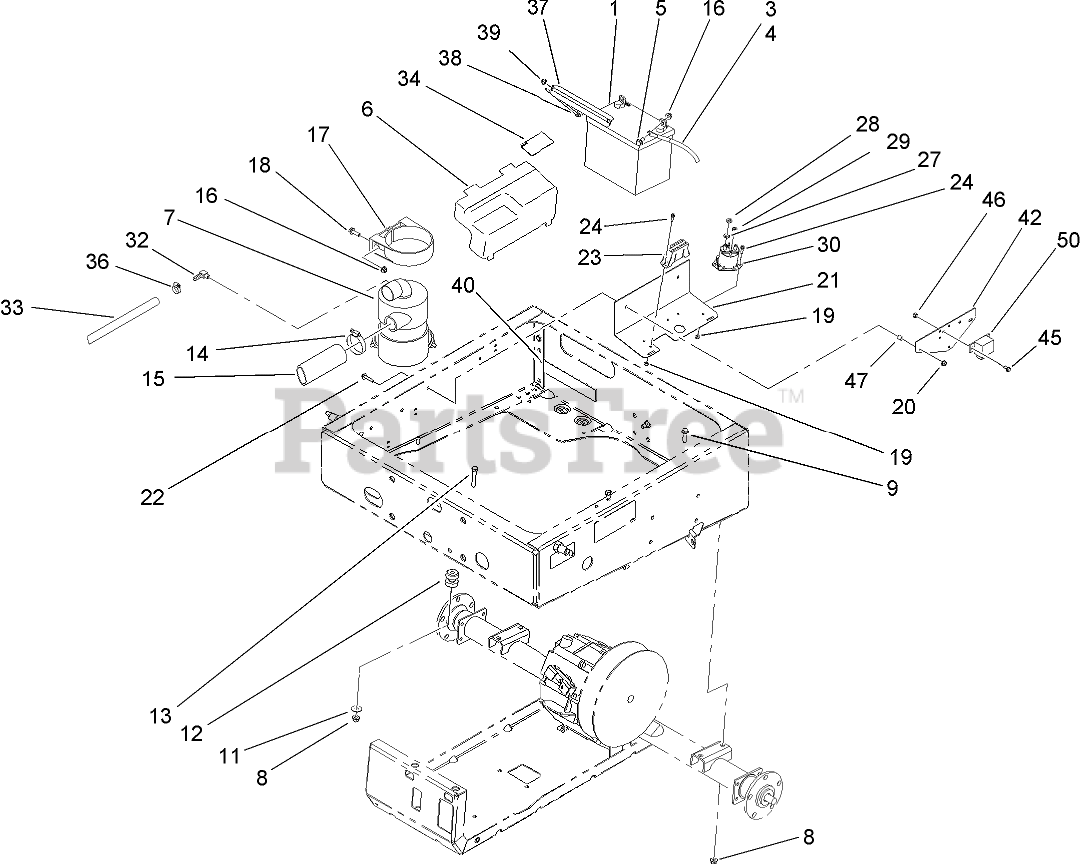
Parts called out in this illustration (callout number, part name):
1	BATTERY-DRY
3	CABLE-NEGATIVE
4	CABLE-POSITIVE
5	SCREW-HHF
6	COVER-ELECTRICAL
7	AIR CLEANER ASM
8	NUT-HF, NI
9	SCREW-HHF
11	WASHER-FLAT
12	MOUNT-ISO
13	SCREW-HH
14	CLAMP-HOSE
15	HOSE-INTAKE
16	NUT-HF, NI
17	BRACKET-MOUNTING
18	SCREW-HHF
19	NUT-LOCK, NI
20	NUT-HHF
21	MOUNT-COMPONENT
22	SCREW-HHF
23	HARNESS-WIRE, MAIN
24	SCREW-HWH
27	WASHER-LOCK
28	NUT-JAM
29	NUT-KEPS
30	SOLENOID
32	FITTING-90 DEG
33	HOSE-BREATHER
34	DECAL-INFORMATION
36	CLAMP-HOSE
37	CLAMP-BATTERY
38	HOOK-RETAIN, BATTERY
39	NUT-HF
40	Pad-Battery
42	BRACKET-IGNITION
45	SCREW-HHF
46	NUT-LOCK, NI
47	SPACER
50	RELAY
